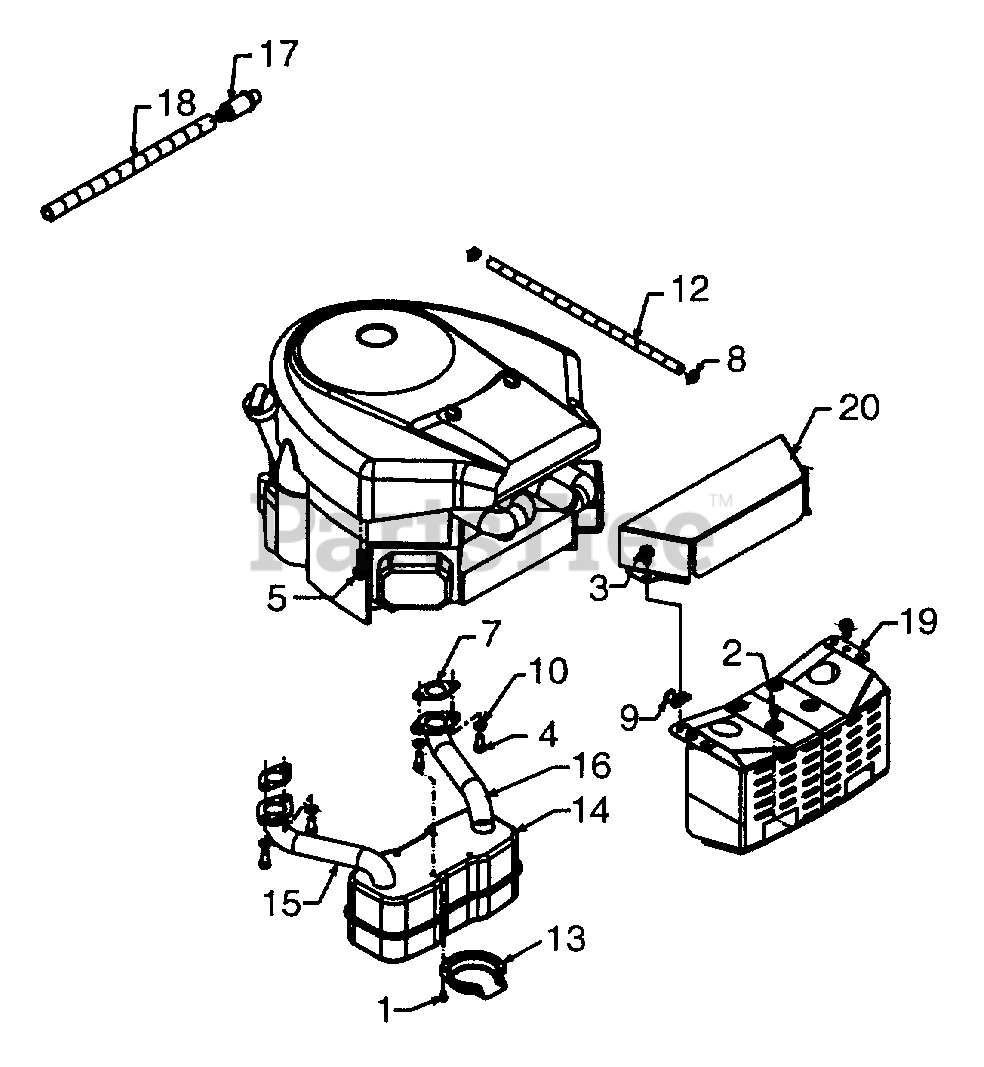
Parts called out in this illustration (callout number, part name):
1	Hex Tap Scr. #8-32 x .38" Lg.
2	Hex Wash. TT-Tap Scr. 1/4-20 x 5" Lg.
3	Hex Wash. TT-Tap Scr. 5/16-18 x .62"
4	Socket Head Scr. 5/16-18 x .62"
5	Hex TT-Tap Scr. 3/8-16 x 1.25"
7	Exhaust Gasket
8	Hose Clamp
9	Clamp
10	Lock Washer 5/16" I.D.
12	Fuel Line 12" Lg.
13	Muffler Deflector
14	Muffler
15	Exhaust Pipe-RH
16	Exhaust Pipe-LH
17	Oil Drain
18	Oil Drain Hose
20	Heat Shield
